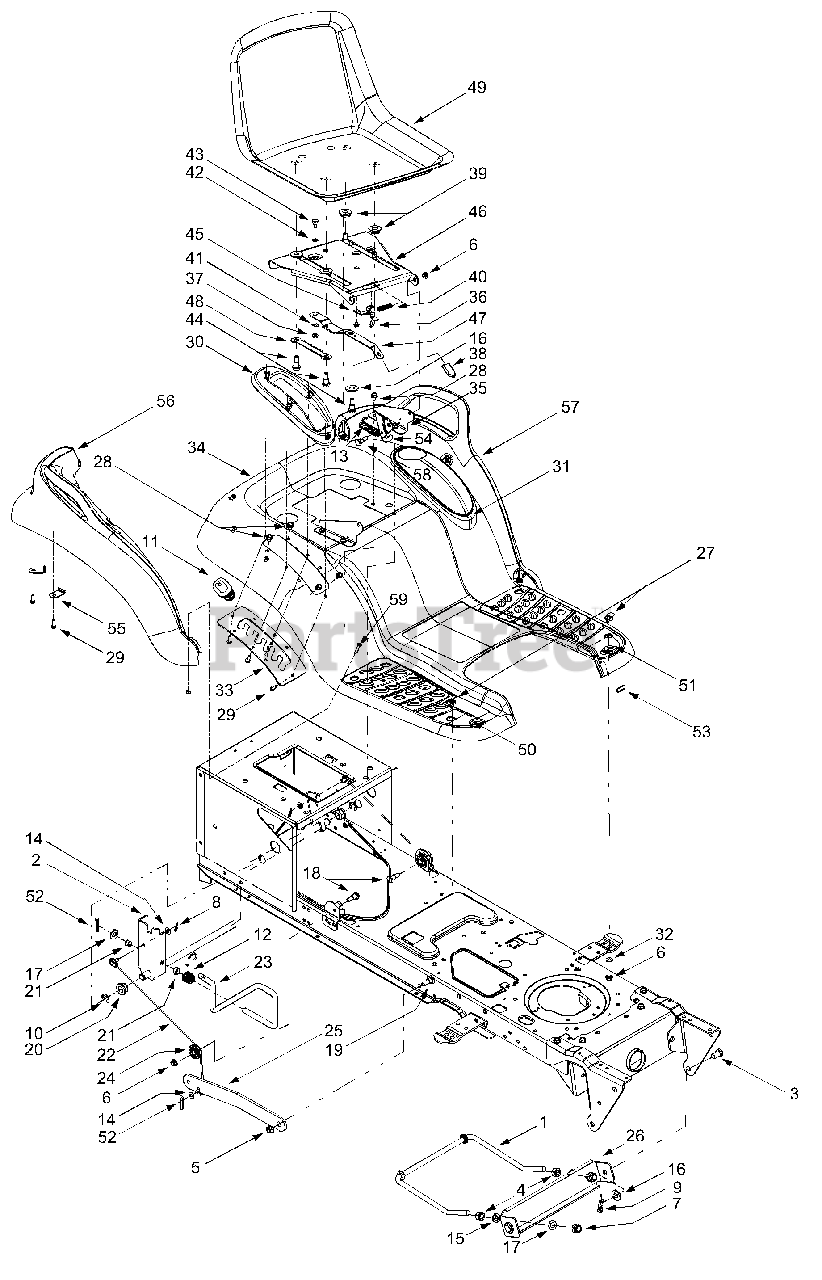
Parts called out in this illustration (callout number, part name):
1	Deck Stabilizer Rod
2	Lift Shaft Assembly
3	Clevis Pin, .5 x .78
4	Hex Nut, 1/2-13
5	Flange Lock Nut, 3/8-16
6	Flange Lock Nut, 5/16-18
7	Hex Nut, 1/2-13
8	Internal Cotter Pin
9	Internal Cotter Pin
10	E-Ring
11	Handle Grip
12	Torsion Spring
13	Extension Spring
14	Flat Washer, 5/16
15	Lock Washer, 1/2
16	Flat Washer, .31 x 1.062 x .134
17	Flat Washer, .51 x 1.12 x .06
18	Hex Cap Screw, 5/16-18 x .62
19	Shoulder Screw, 3/8-16
20	Hex Flange Bearing
21	Snap Flange Bearing
22	Lift Cable, 16.16
23	Lift Handle
24	Roller Pulley
27	Carriage Bolt, 5/16 x .62
28	AB Screw, 5/16-12 x .75
29	Self-tapping Screw, 1/4-15 x .75
30	Lift Lever Cover
31	Cover w/ Cup Holder
32	Flat Washer, .349 x 1.0 x .063
36	Screw, #10-16 x .375
37	Hex Flange Lock Nut, 1/4-20
38	Seat Adjuster Grip
39	Spacer
40	Compression Spring, .41 x 1.5
41	Spring Washer, .265 x .562 x .025
42	Flat Washer, .344 x .62 x .03
43	Shoulder Screw, .340 x .285,1/4-20
44	Shoulder Screw
45	Seat Stop
48	Seat Adjustment Selector
49	Seat, Yellow
50	RH Foot Pad
51	LH Foot Pad
52	Cotter Pin
53	Trim Strip
54	Seat Lift Bracket
55	Fender Clips
55	Carriage Bolt 1/4-20 x 1.0" Lg.
55	Hex Nut 1/4-20 Thd.
56	Fender Flare RH
57	Fender Flare LH
58	Shoulder Screw
58	Lock Nut 5/16-18
59	Carriage Screw 1/4-20 x 1.0"
